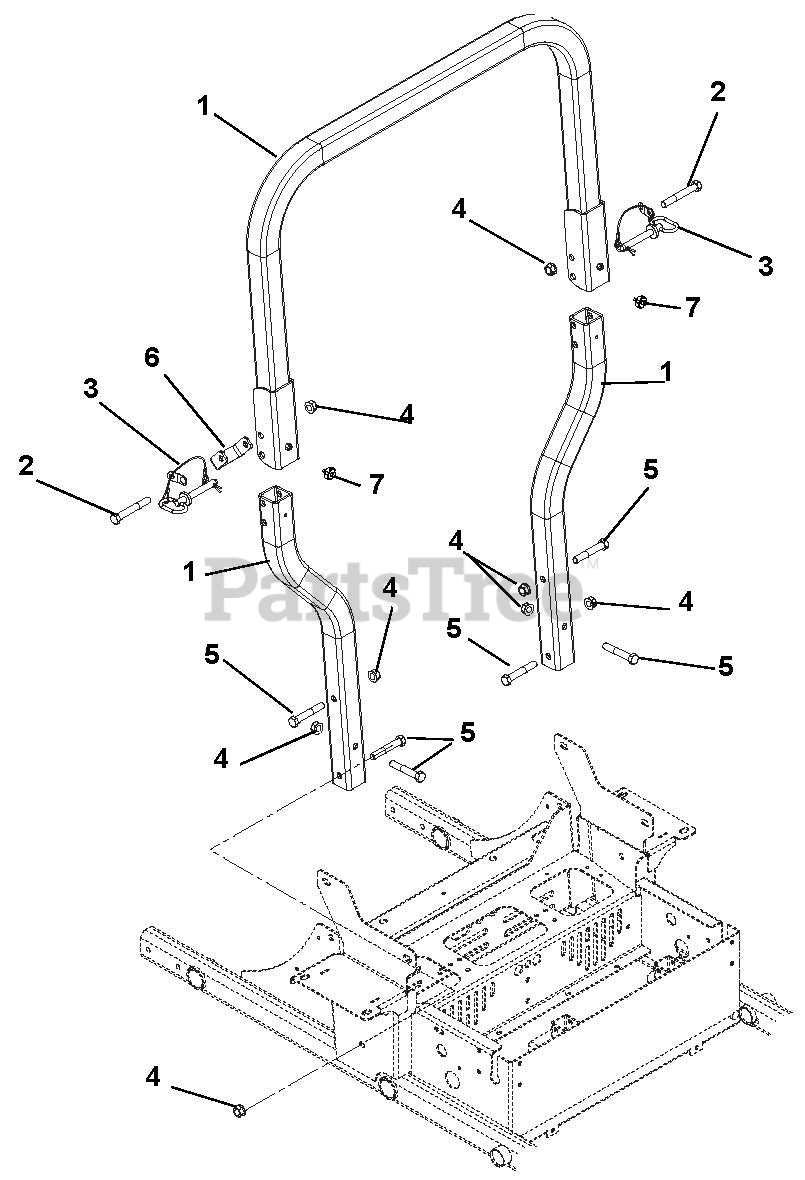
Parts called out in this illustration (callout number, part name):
1	ROPS, PT200 REPLACEMENT
2	BLT-HEX .50-13X3.50 GR5 YWZC
3	ASSY, ROPS PIN/LANYARD
4	NUT-LK-TOP-FLG .50-13 YWZC
5	BLT-HEX .50-13X3.00 GR5 YWZC
6	BRKT, ROPS STOP, PRO-TURN YZ
7	KNOB, ROUND 5/16-18 X .750
